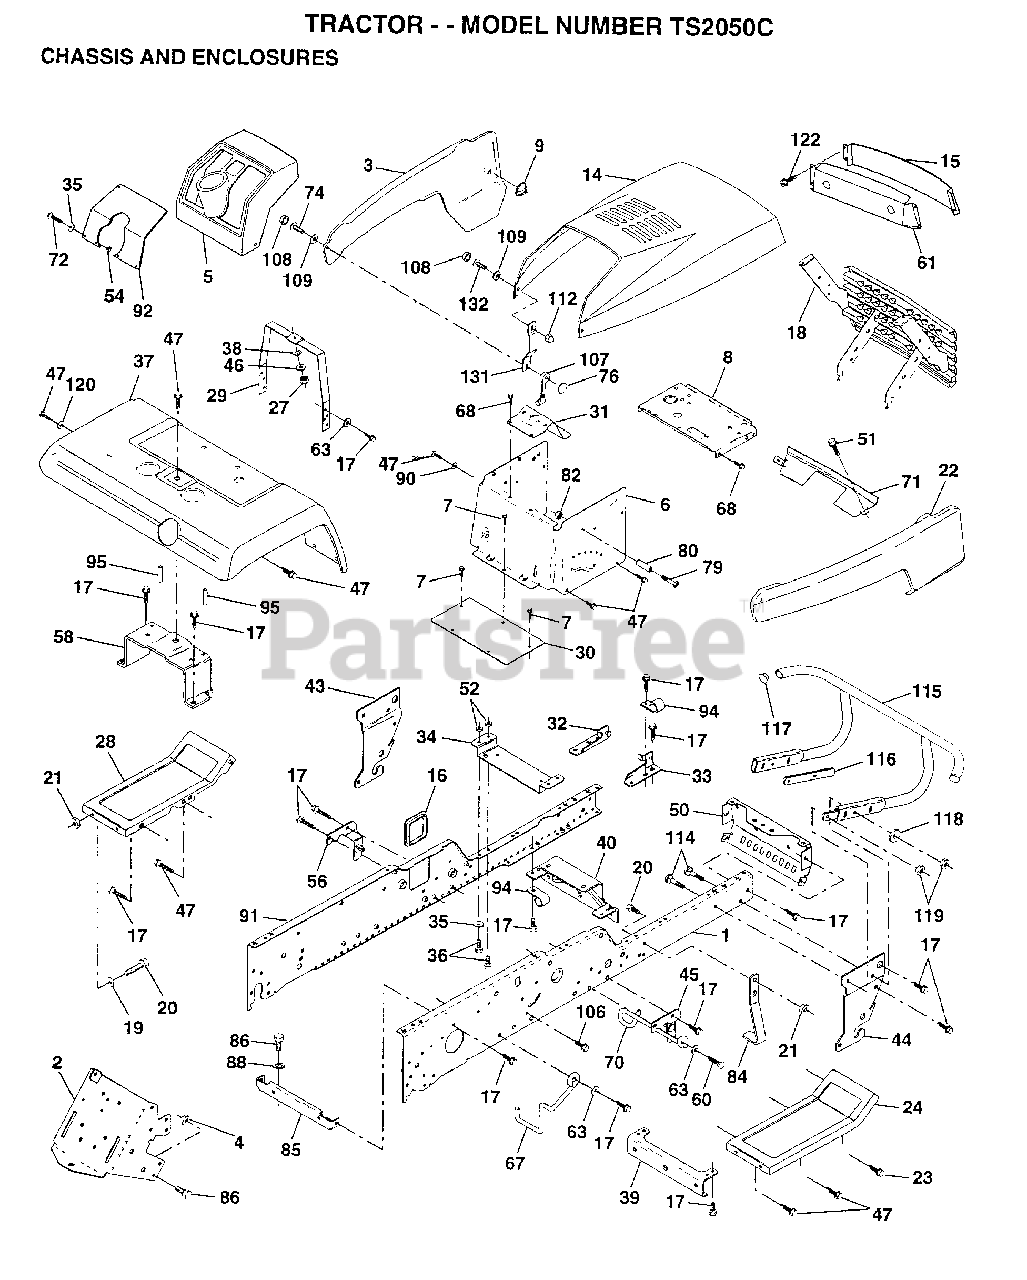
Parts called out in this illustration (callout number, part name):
1	"RAIL,FRAME RH"
2	DRAWBAR GT
3	PANEL ASM SIDE LH
4	NUT.7/16
5	DASHBOARD BLACK
6	"DASH AS.,LOWER"
7	SCREW
8	SUPPORT.DASH.BTRY
9	PAL NUT LT
15	LENS.BAR.CLEAR
16	COVER ACCESS
17	SCREW
19	WASHER
20	BOLT
23	SCREW GTV
24	FOOTREST.RH.LT/GT
28	FOOTREST.LH.LT/GT
29	DASH.SUPT.YP/HUSQ
30	SADDLE.SCR.6SP
31	BRAKET.SUPT.STEER
32	BRACKET ASM FRAME
33	BRACKET ASM FRAME
34	BRACKET.ENG.SUPT.
35	WASHER
36	BOLT
37	FENDER
38	LOCKWASHER
39	BRACKET.AXLE.FRT.
43	BRACKET.SUS.FT.LH
44	BRACKET.SUS.FT.RH
46	WASHER PM
47	SCREW LT
50	"BRKT CHASSIS,FRNT"
51	SCREW CRT
58	BRKT.ASM.FENDER
60	SCREW
61	BEZEL.ASM.
63	WASHER
67	GUIDE BELT TRANS
68	SCREW LT
70	GUIDE.BELT.MID.SP
71	STRAP.GRILLE.PNT.
72	SCREW
74	SCREW
76	WELDNUT
79	SCREW
80	SPACER LT
84	STOP.OVER.CENTER
85	BRACKET.SUPT.TRAN
86	BOLT
88	LOCKWASHER
90	LOCKWASHER
91	"RAIL,FRAME LH"
92	PLATE YP SLKSCR
94	CLIP GTV
95	NUT-PUSH YT
107	HOOD LATCH T
108	SNAP CAP LT
109	WASHER LT
112	ACORN NUT RB
114	BOLT.3/8-14X1.25
115	BUMPER.ASM
116	BRACKET.EXT.BUMP.
117	PLUG.PLASTIC
118	WASHER
120	WASHER HYT
131	BKT.SPT.HOOD/PANL
132	SCREW.10-24X3/8.
